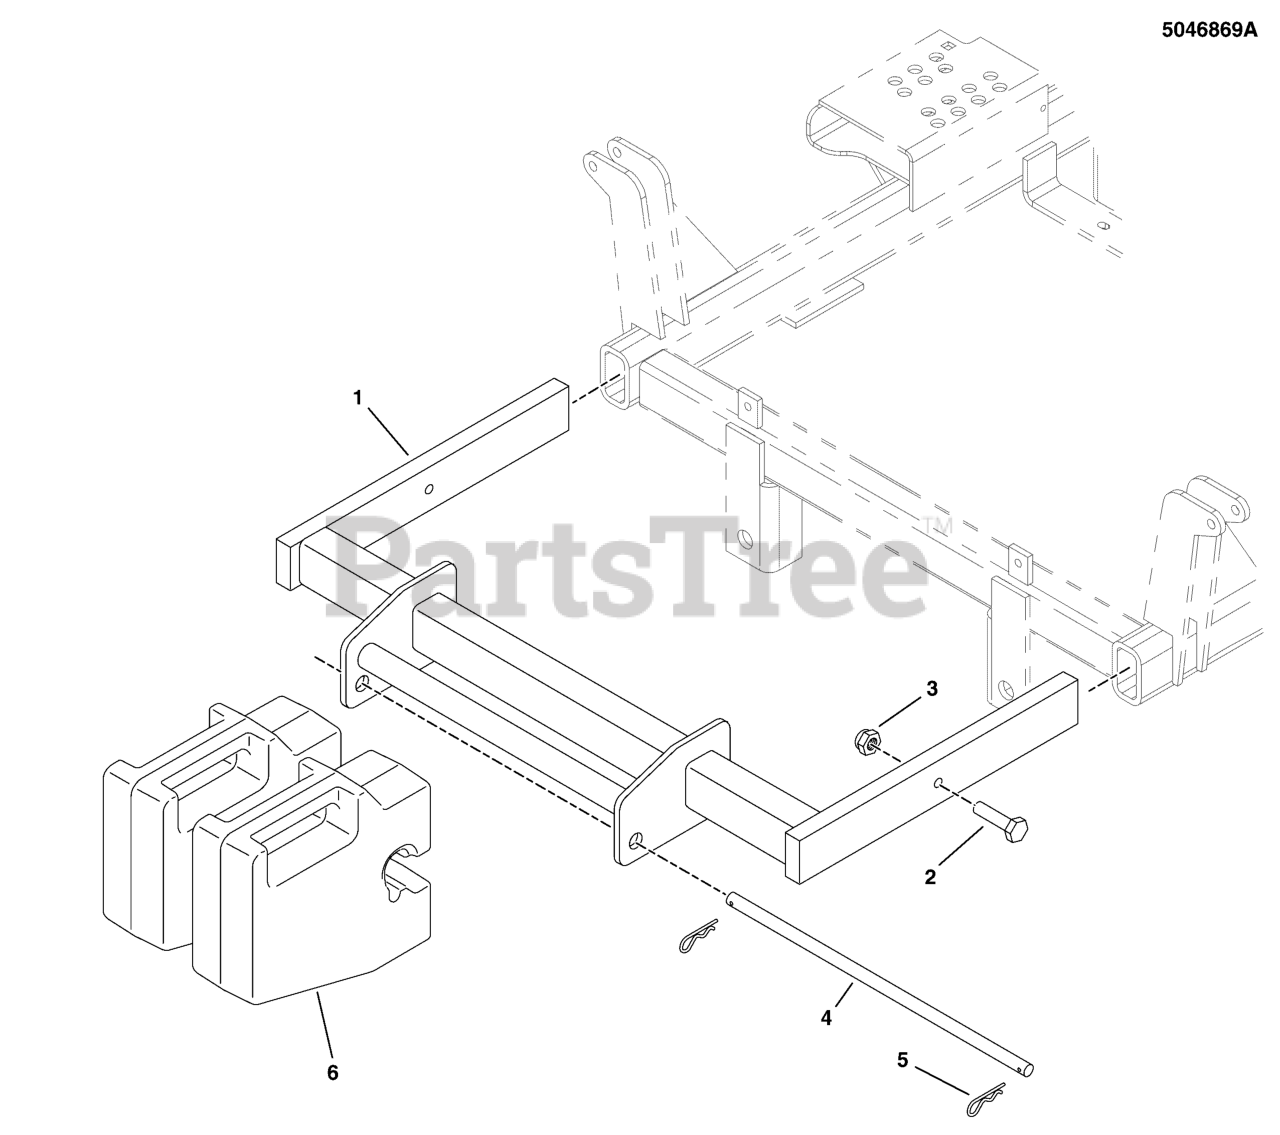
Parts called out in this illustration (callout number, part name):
1	3-BAG WEIGHT RACK WELDMENT
2	BOLT, 3/8-16 X 2, GD5, CZ
3	NUT, 3/8-16 HEX NYLON LOCK
4	ROD, WEIGHT RETAINER
5	PIN, HAIR, .0915 X 1-7/8
6	WEIGHT-QUICK ATTACH 50LB SUITCASE PAINTED
